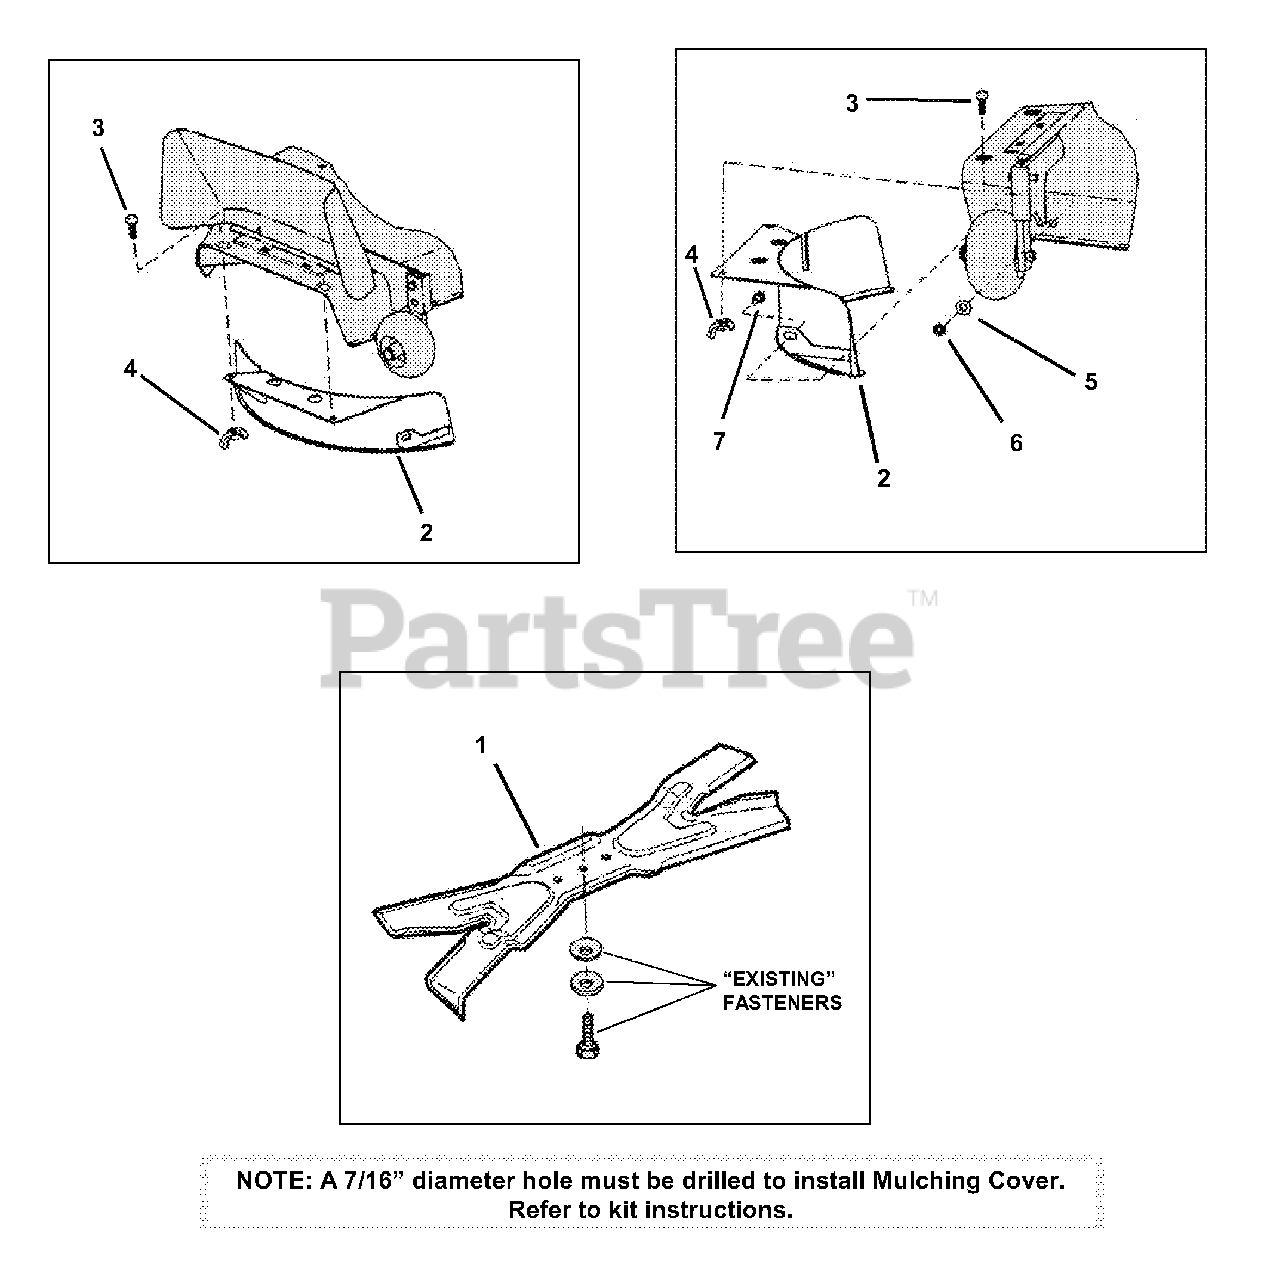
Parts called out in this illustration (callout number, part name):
1	BLADE, 21" Ninja (Quad Edge)
2	WELDMENT, Mulching Cover
3	BOLT, 5/16-18 x 3/4" Square Neck Carriage, Grade 5
4	WING LOCKNUT, 5/16-18
5	WASHER, 3/8" Flat
6	NUT, 3/8-16 Hex Center Lock, Grade 5 or B
7	BOLT, 3/8-16 x 3/4" Hex Flange Lock, Grade 5
